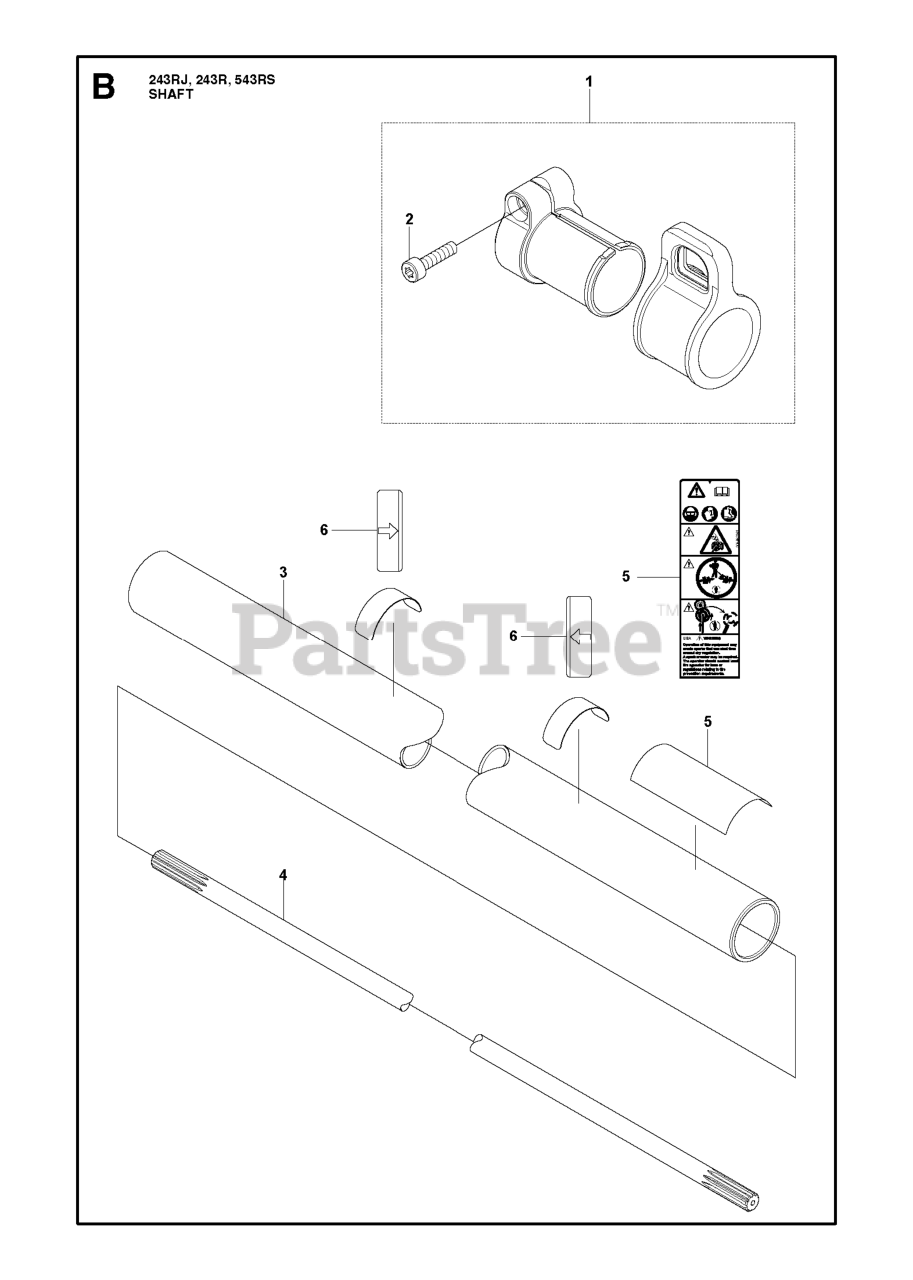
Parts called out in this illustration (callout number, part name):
1	HANGER ASSY.
2	BOLT
4	DRIVE SHAFT
5	LABEL WARNING TRIMMERS AND BRU
